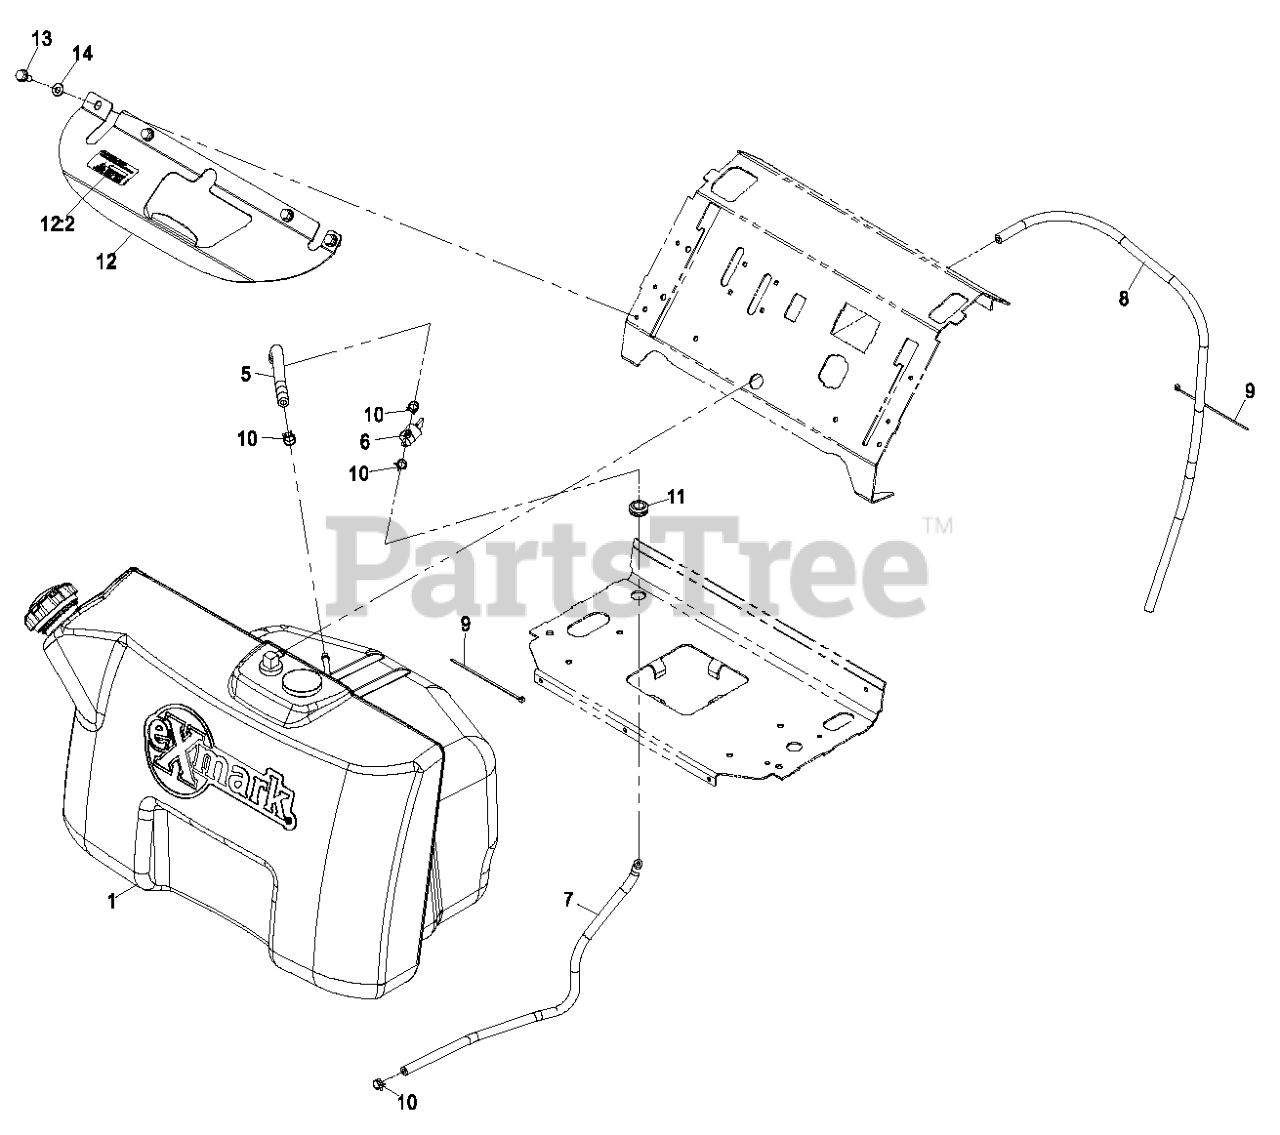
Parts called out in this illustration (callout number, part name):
5	HOSE-FUEL
6	VALVE-FUEL
7	HOSE-FUEL
8	HOSE-FUEL
9	TIE-CABLE
10	CLAMP-HOSE
11	GROMMET
12	BRACKET-TANK
12:2	DECAL-FILL, FUEL
13	SCREW-THD ROLL, HWH
14	WASHER-FLAT
